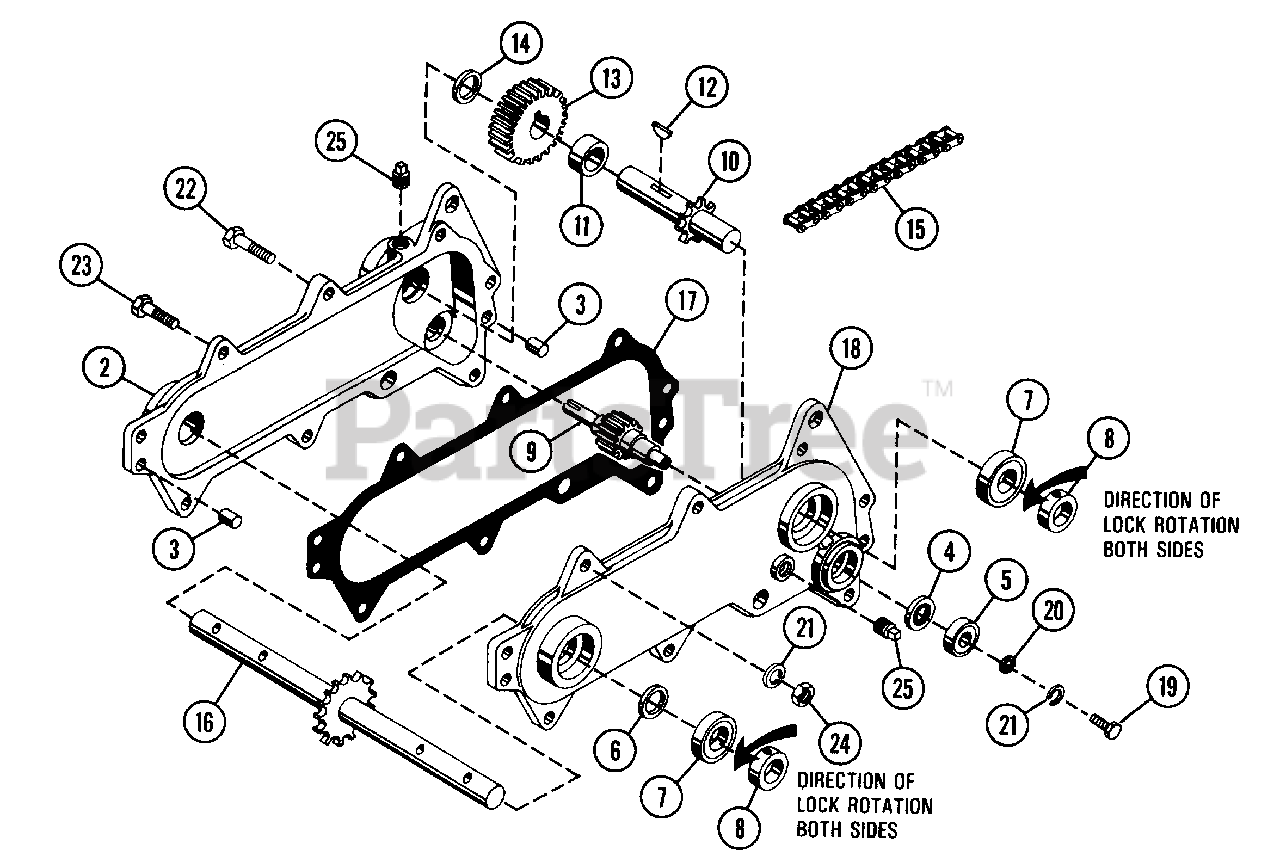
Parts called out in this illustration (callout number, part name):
1	CHAIN CASE ASM.
2	CHAIN CASE
3	DOWEL PIN
4	OIL SEAL
5	RADIAL BRG.
6	OIL SEAL
7	BALL BRG.
8	COLLAR
9	DRIVE SHAFT
10	DRIVEN SHAFT
11	SPACER
12	KEY, WOODRUFF .250X1.00 HRD #15
13	GEAR, 47T
14	SPACER
15	ROLLER CHAIN
16	TINE SHAFT
17	GASKET
18	CHAIN CASE COVER
19	BOLT, HEX 5/16-18X.75
20	WASHER, FLAT .344X.688X.065
21	WASHER, LOCK 5/16 REG.6
22	BOLT, HEX 5/16-18X2
23	BOLT, HEX 5/16-18X1.50
24	NUT, HEX 5/16-18
25	PIPE PLUG
